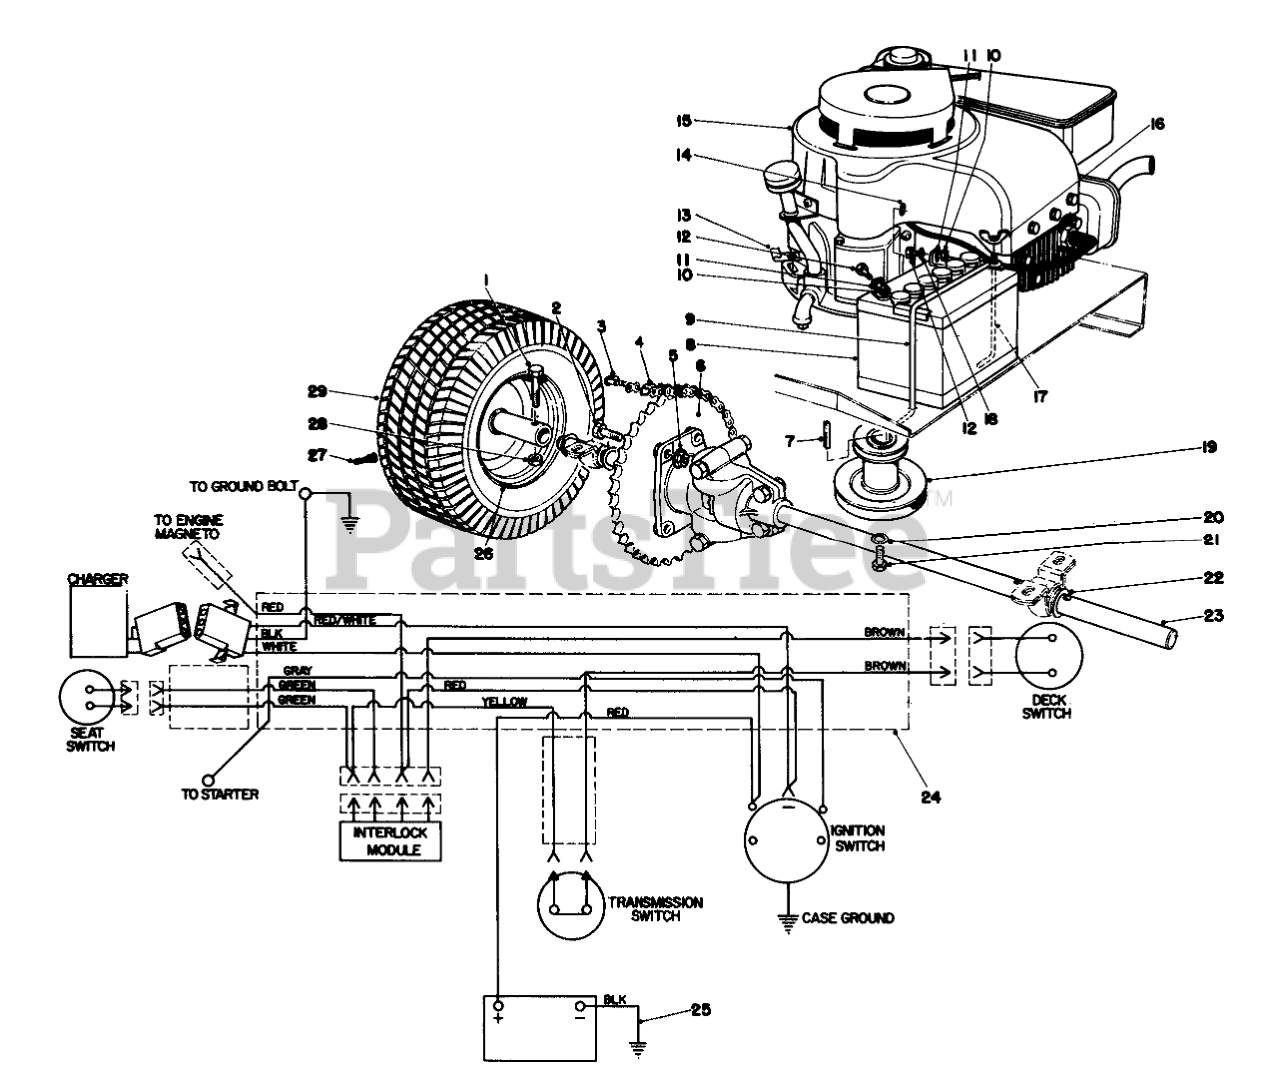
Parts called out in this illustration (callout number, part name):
1	SCREW-HH
2	SCREW-HH
3	LINK-CONNECTING
4	Chain Roller (Incl. Ref. #3)
5	NUT-LOCK, CONE
6	Sprocket
8	BATTERY
9	Battery Clamp
10	NUT-HEX
11	WASHER-LOCK
12	SCREW-HH
14	WASHER-LOCK/EXT
15	Engine
16	NUT-WING SPECL
17	ROD-SUPPORT, BATTERY
18	WASHER-FLAT
19	Engine Pulley
20	WASHER-LOCK
21	SCREW-HH
22	WASHER
23	Differential
24	Wiring Harness
25	ENG-GROUND WIRE ASM
27	STEM-VALVE
28	NUT-LOCK, CONE
29	Tire
